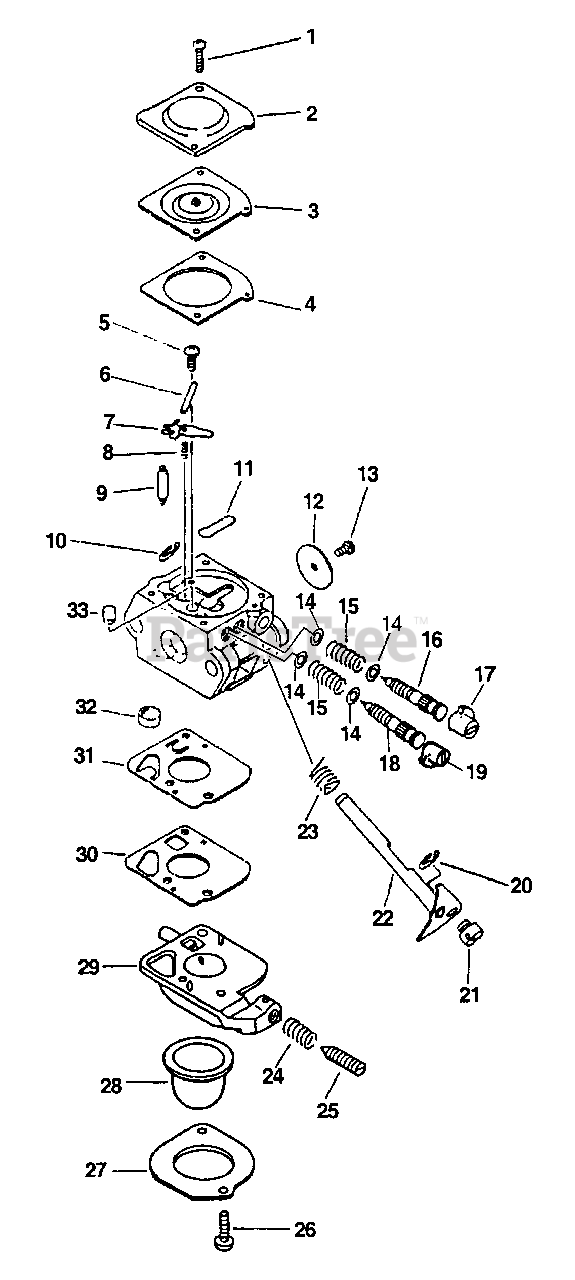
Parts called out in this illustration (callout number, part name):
2	COVER, METERING DIAPHRAGM
3	DIAPHRAGM, METERING
4	GASKET, METERING
5	SCREW, METERING LEVER PIN
6	PIN, METERING LEVER
7	LEVER, METERING
8	SPRING, METERING LEVER
9	VALVE, NEEDLE
11	PLUG, WELCH
12	VALVE, THROTTLE
15	SPRING, NEEDLE
16	NEEDLE, MIXTURE
17	CAP, LIMITER - WHITE
18	NEEDLE, HIGH SPEED
19	CAP, LIMITER - RED
22	SHAFT, THROTTLE
23	SPRING, THROTTLE RETURN
25	SCREW, THROTTLE ADJUST
27	RETAINER
28	BULB, PURGE
29	BODY ASSY, PURGE
30	GASKET, PUMP
31	DIAPHRAGM, PUMP
32	STRAINER
33	NOZZLE, CHECK VALVE
